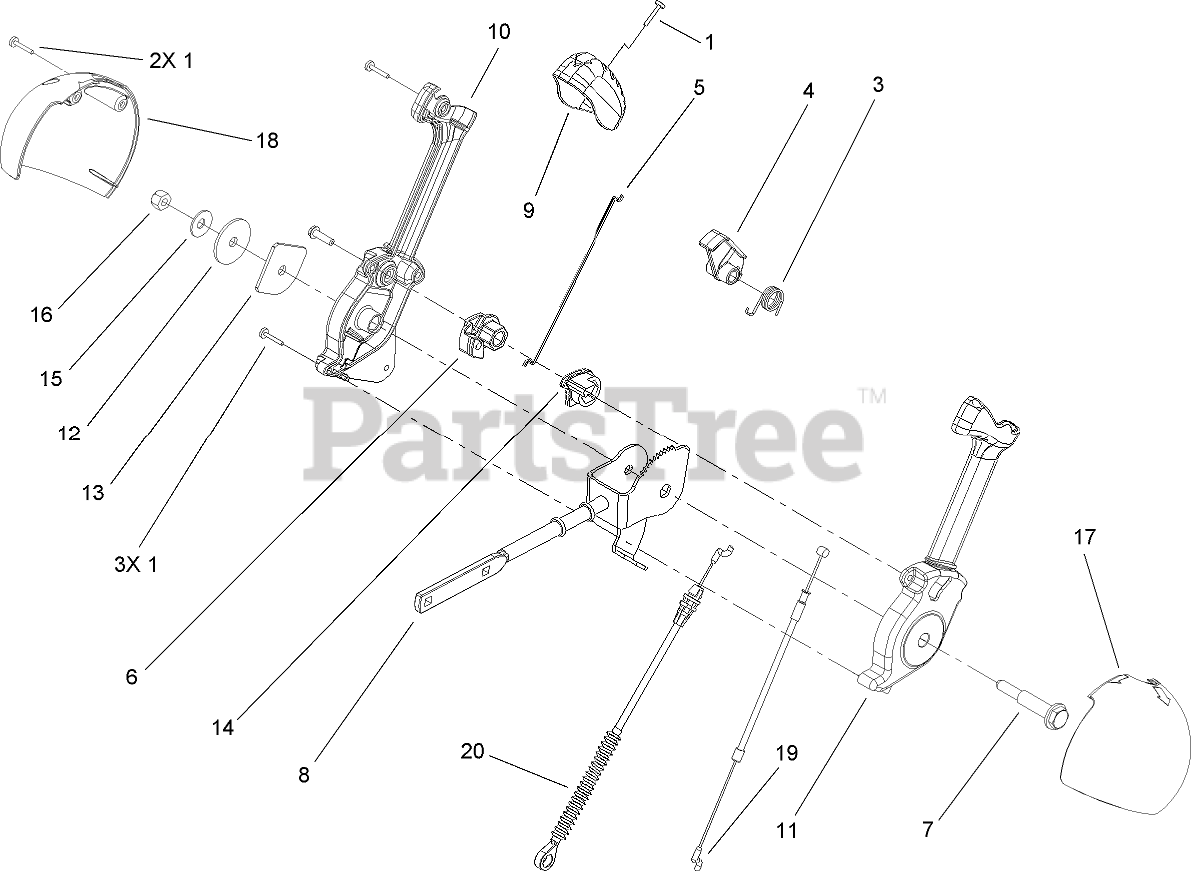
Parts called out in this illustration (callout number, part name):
1	SCREW-PPH
3	SPRING-TORSION
4	TRIGGER-LATCH
5	LINK-LATCH
6	LEVER-CABLE, DEFLECTOR
7	SCREW-SHOULDER
8	ROD-CONTROL, CHUTE
9	CAP-LEVER
10	LEVER-CONTROL, CHUTE (RH)
11	LEVER-CONTROL, CHUTE (LH)
12	WASHER-NYLON
13	PLATE-FRICTION
14	PAWL-LATCH
15	WASHER-BELLEVILLE
16	NUT-LOCK, NI
17	COVER-LEVER, CHUTE (LH)
18	COVER-LEVER, CHUTE (RH)
19	CABLE-RELEASE, CHUTE
20	CABLE-CONTROL, DEFLECTOR
